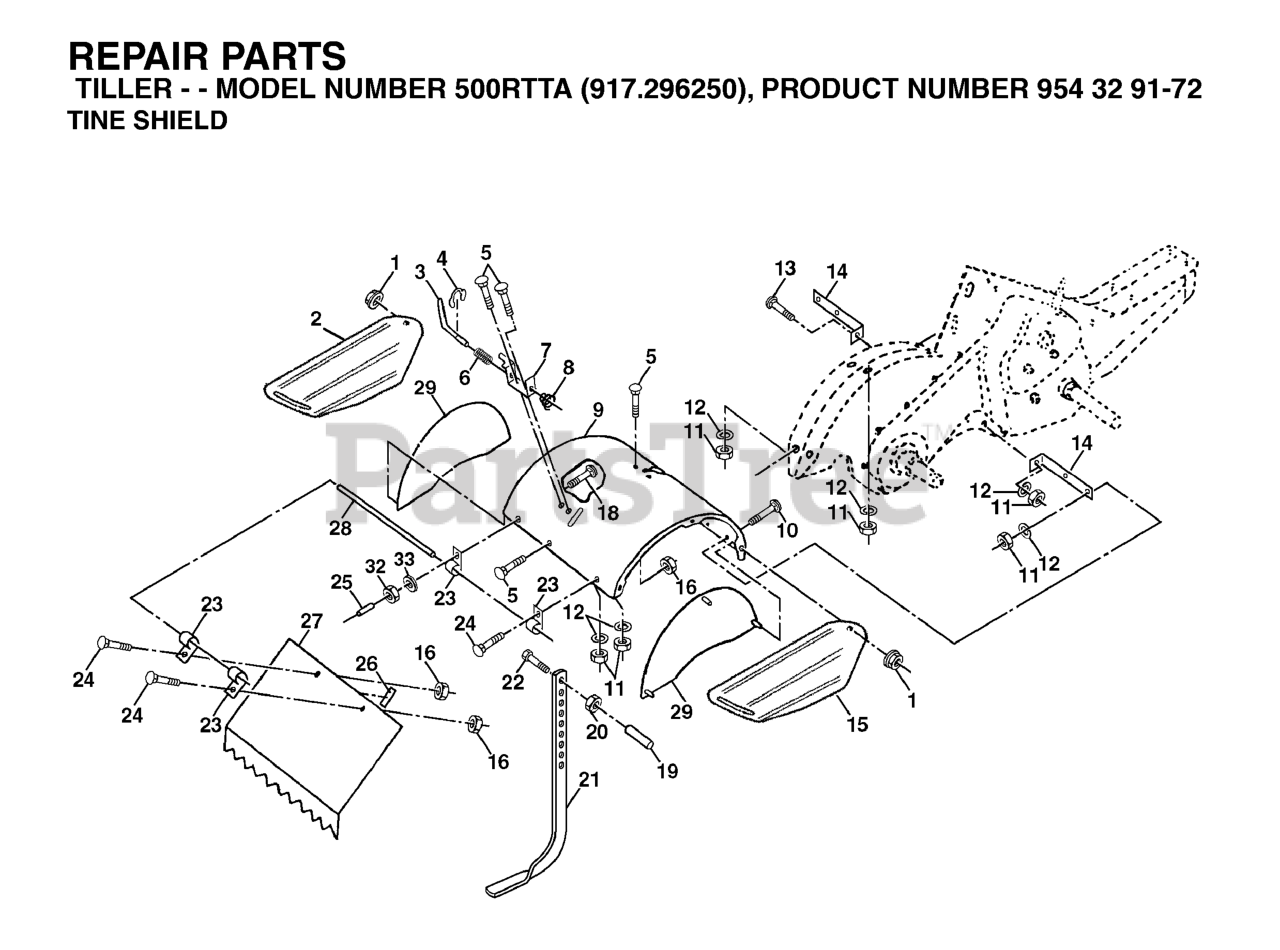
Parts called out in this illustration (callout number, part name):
1	NUT LOCK HEX FLANGE 5/16-18
2	SHIELD
3	STAKE PIN TI
4	RING, KLIP
5	BOLT, RDHD SQNK 5/16-18 X 3/4
7	BRACKET.LATCH.STAKE.3.20.BLACK
8	SPRING CRT
9	SHIELD, TINE
12	WASHER.LOCK.HVY.HLCL.SPR.5/16
13	BOLT.CARRIAGE.5/16-18
14	BRACKET.TINE.SHIELD.TILLER
15	SIDE SHIELD RH
16	NUT T
20	NUT.HEX.3/8-16UNC
21	STAKE.DEPTH.16.CRT.BLACK
22	BOLT.375-16
25	VINYL CAP TI
26	PAD IDLER TI
27	SHIELD LEVELING
28	PIN.HINGE.TILLER
29	SHIELD SIDE
32	NUT
33	LOCKWASHER
